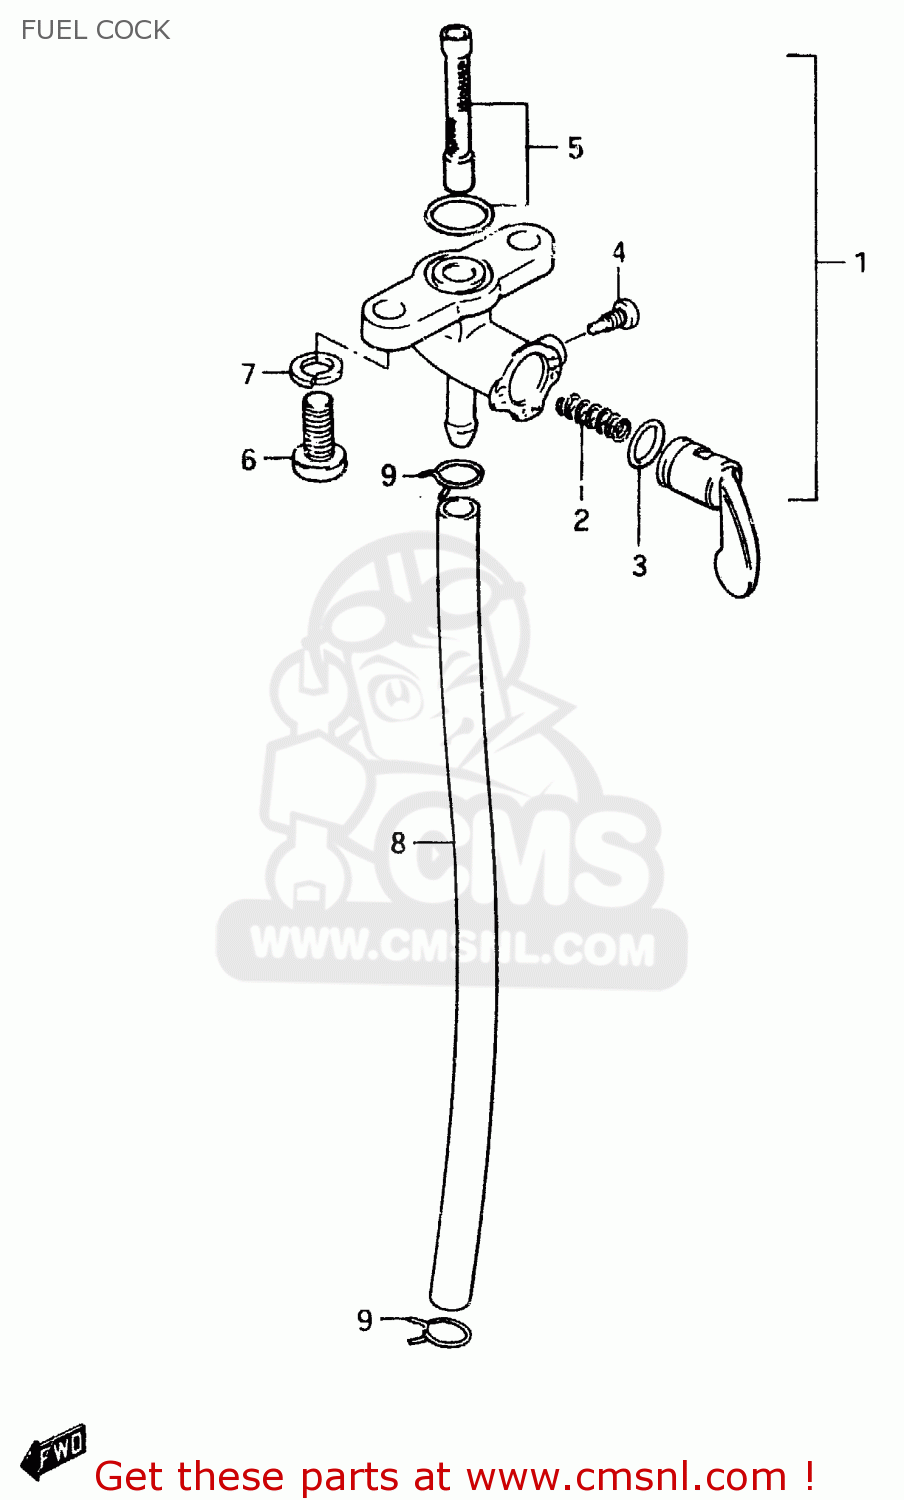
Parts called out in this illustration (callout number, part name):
1	COCK ASSY,FUEL
2	SPRING,FUEL COCK VALUE
3	O RING,LEVER
4	SCREW
5	FILTER SET FUEL
6	SCREW
7	LOCK WASHER
8	HOSE,FUEL
9	CLIP
